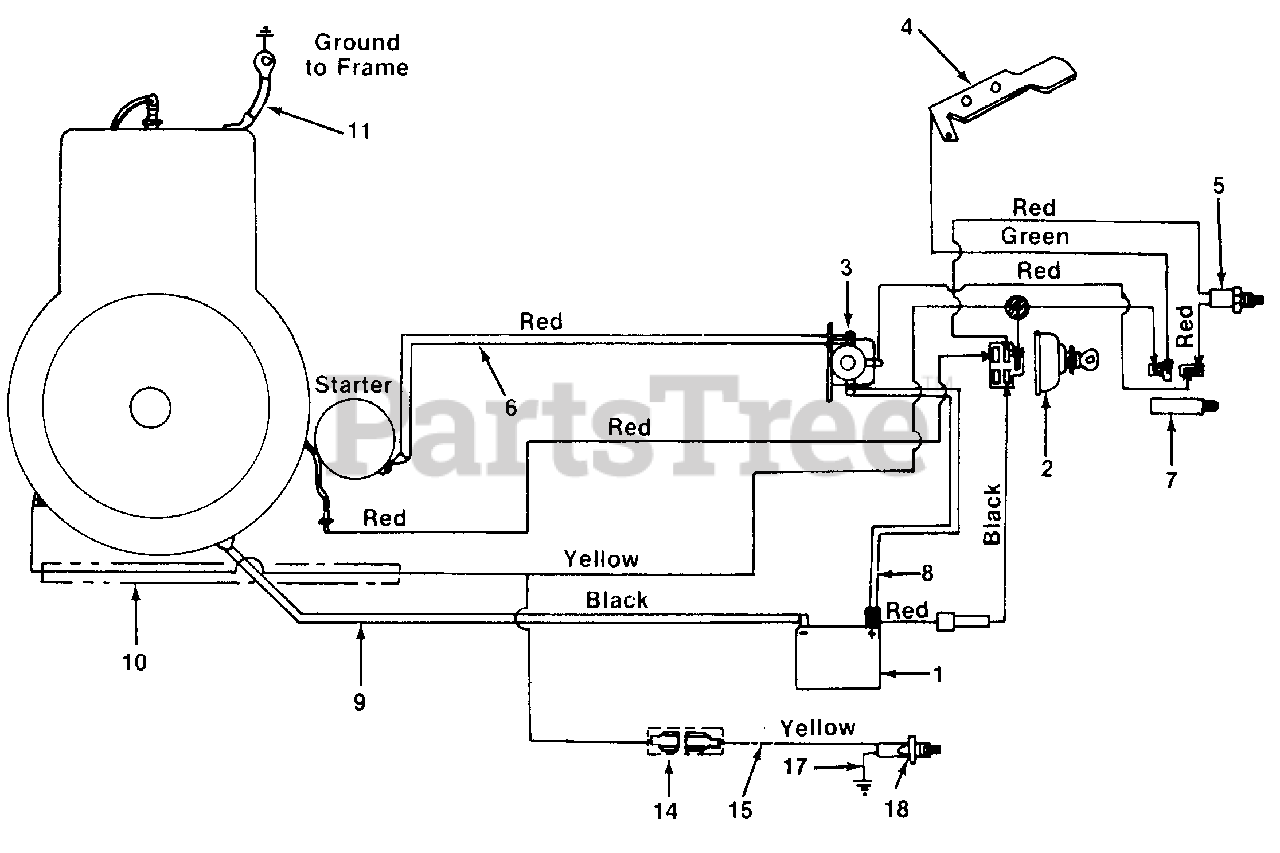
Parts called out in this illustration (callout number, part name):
1	Battery
2	Key Switch
3	Solenoid
4	Spring Switch
5	Safety Switch
6	Electric Wire
7	Safety Switch
8	Electric Wire 13.5" Lg.
10	Convoluted Conduit 24" Lg.
14	Tab Receptacle
15	Wire Lead 12" Lg.
18	Safety Switch
